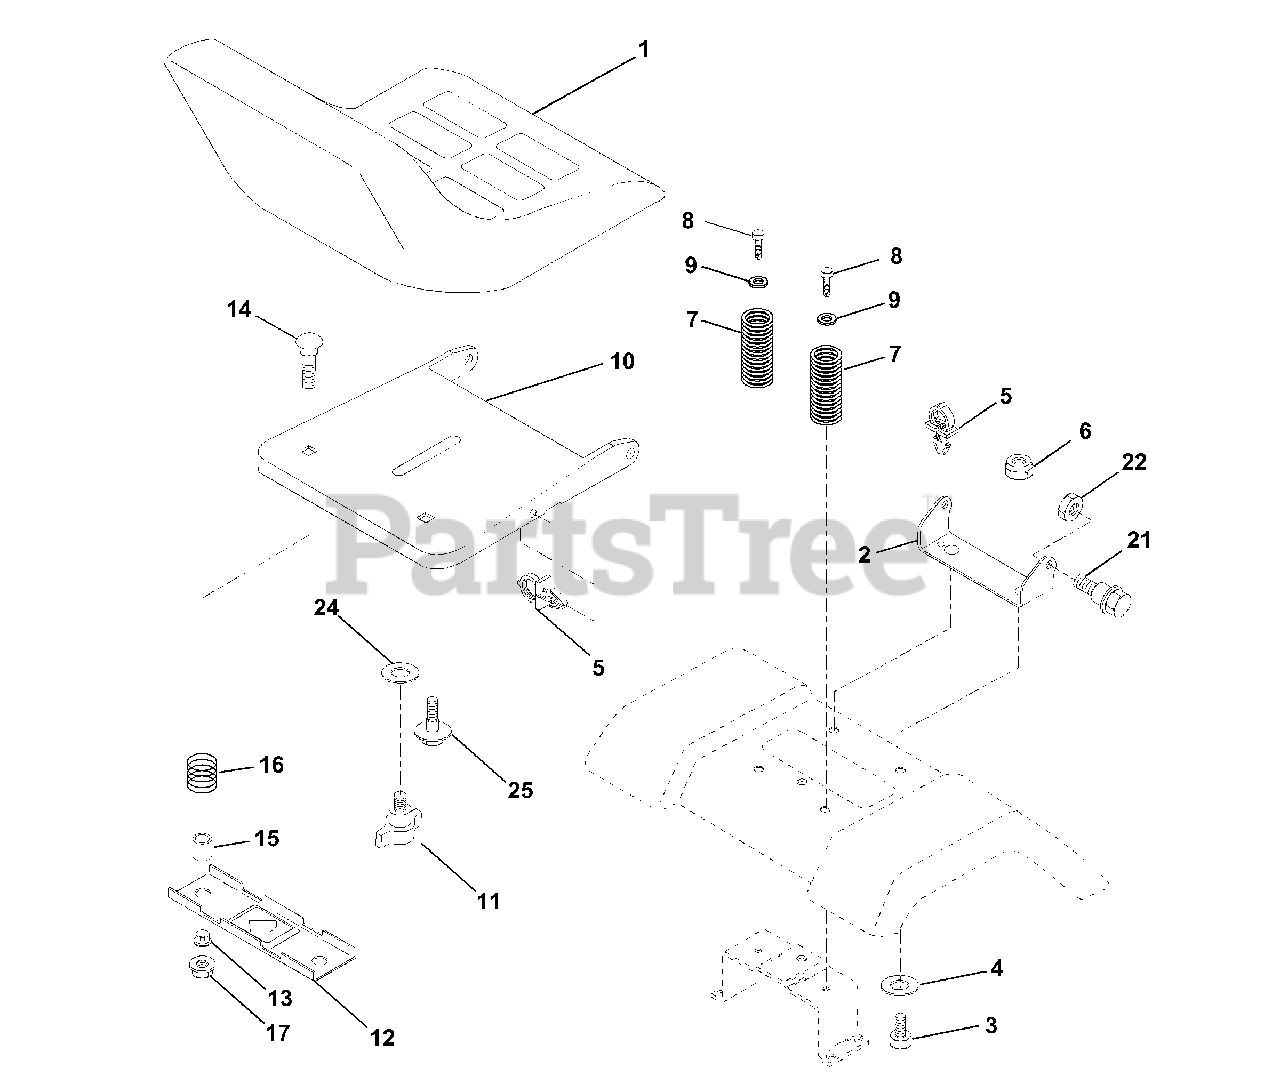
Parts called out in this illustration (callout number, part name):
2	Bracket Pvt St
3	Bolt Fin Hex 3/8-16unc x 1
4	Washer Flat 13/32 x1 x10 Ga
5	Clip Push-In Hinged
6	Locknut Hex W/Wsh 3/8-16
7	Spring Seat Cprsn 2 250 Blk
8	Screw 3/8-16 x 1
9	Washer 13/32 x 1 x 14 Ga
10	Pan Seat
11	Knob Seat Adj. Wingnut
12	Bracket Mounting Switch
13	Bushing Snap Blk Nyl 50 Id
14	Bolt Rdhd Sht 1/4-20x1-1/2
15	Spacer Split 28x 96 Yel Zinc
16	Spring Cprsn 1 27 Blk Pnt
17	Nut Lock 1/4 Lge Flg Gr 5
21	Bolt Shld 5/16-18 Unc
22	Nut Lock Hex W/Ins 5/16-18
24	Washer 17/32 x1-3/16x12 Ga
25	Bolt Shoulder 5/16-18 x 62
